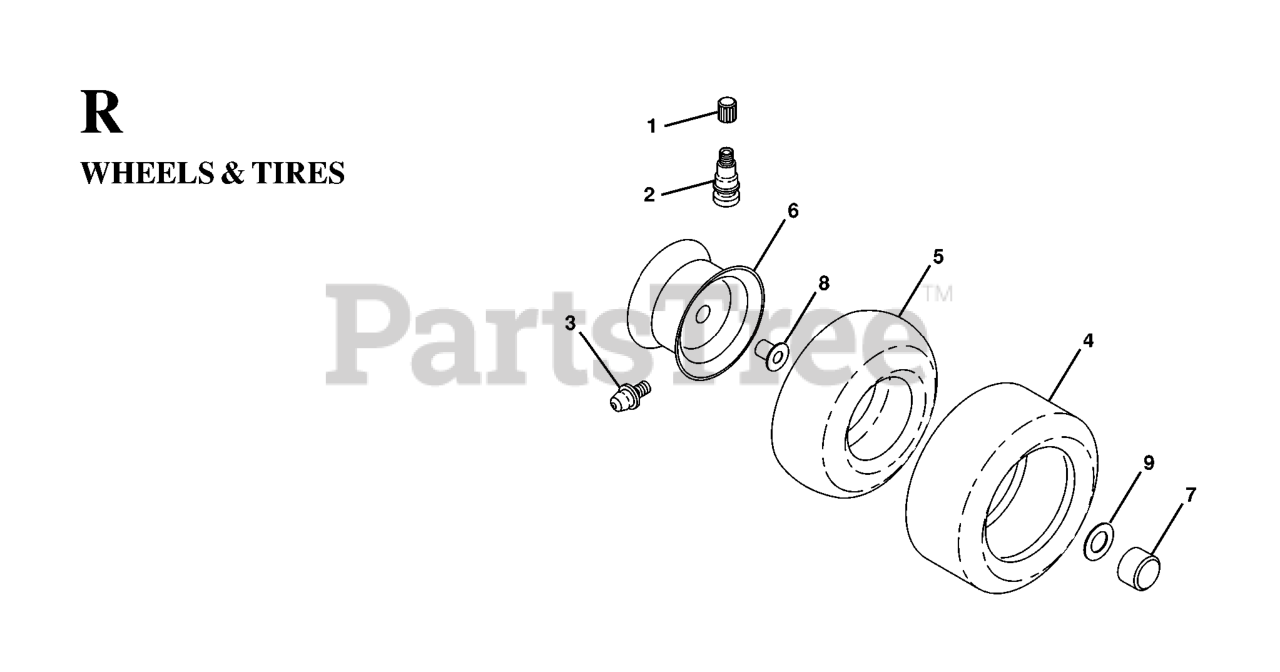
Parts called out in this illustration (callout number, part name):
2	VALVE STEM LT
3	FITTING LT
4	TIRE FRONT 15X6-6
5	TUBE.5.3/4.5/6
5	TUBE.16X6.5/7.5-8
6	RIM REAR 8"
6	RIM
7	CAP.HUB.FRONT.LT.BLACK
8	BEARING T
